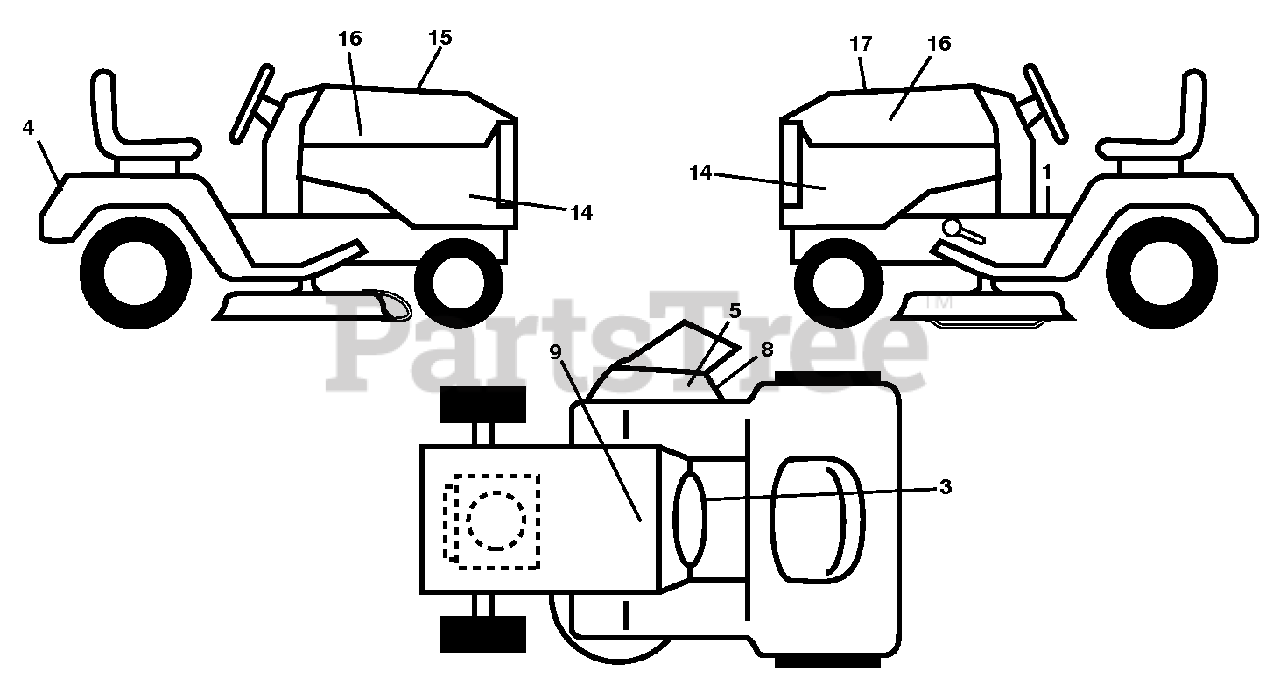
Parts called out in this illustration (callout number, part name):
1	DECAL.WARN.STARTINST.LOWEARIEN
3	DECAL, WARNING SPARK ARRESTOR
4	DECAL.FENDER
5	DECAL.MOWER.WARN.KEEP.HAND.AWY
8	DECAL.MOWER.SCH.48/54.PREM
9	DECAL BTRY SYMBOLS
14	DECAL.SIDE.PANEL.LGT2654.2013
15	DECAL.WARNING.CUST.RESP.E85.
16	DECAL.BADGE.170MM.TEXTLOGO.
17	DECAL.RPL.KH.KT7.TGW.54.K46
18	DECAL.BYPASS.FENDER.CRD/LT/YT
19	DECAL.E85.WARNING.2012
21	PAD.FOOTREST.HUSQ.GT.LH
22	PAD.FOOTREST.HUSQ.GT.RH
